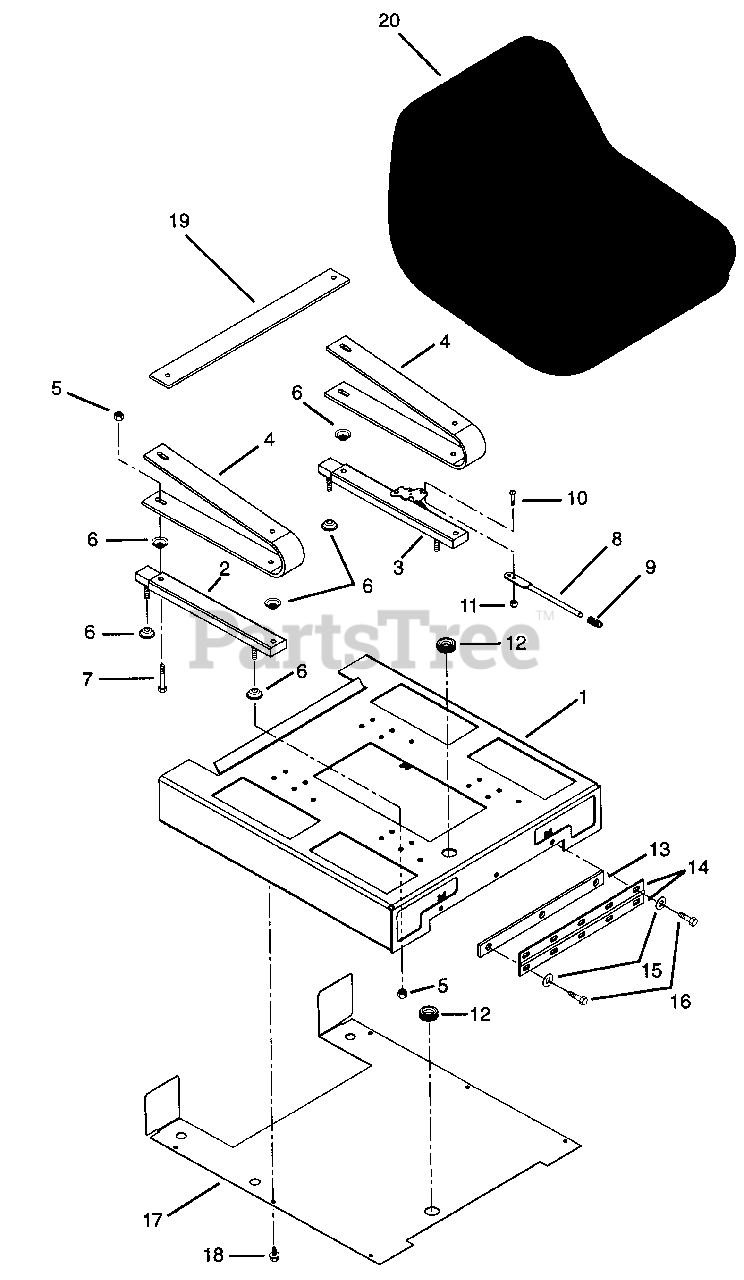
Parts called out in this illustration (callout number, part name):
1	Weldment,Seat Lid
2	Adjuster,Seat
3	Adjuster,Seat w/Latch
4	Spring,Seat
5	Nut-Locking-Nylon .312-18 Grade 2
6	Seat Slide Spacer
7	Bolt-Hex .31-18 x 1.38
8	Seat Slide Handle
9	Tip-Brake Lock Lever
10	Screw-Machine 10-24 x .625
11	Nut-Locking 10-24 Nylon
12	Grommet 75 x 1.06 x 1.38
13	Plate,Clamping
14	Hinge
15	Washer-Flat-Steel .344 x .688 x .065
16	Bolt-Hex .31-18 x .75 Grade 5
17	Shield,Seat Lid
18	Screw-Tapping .25-20 x .50
19	Bracket,Seat
20	Seat,V-560 High Back
